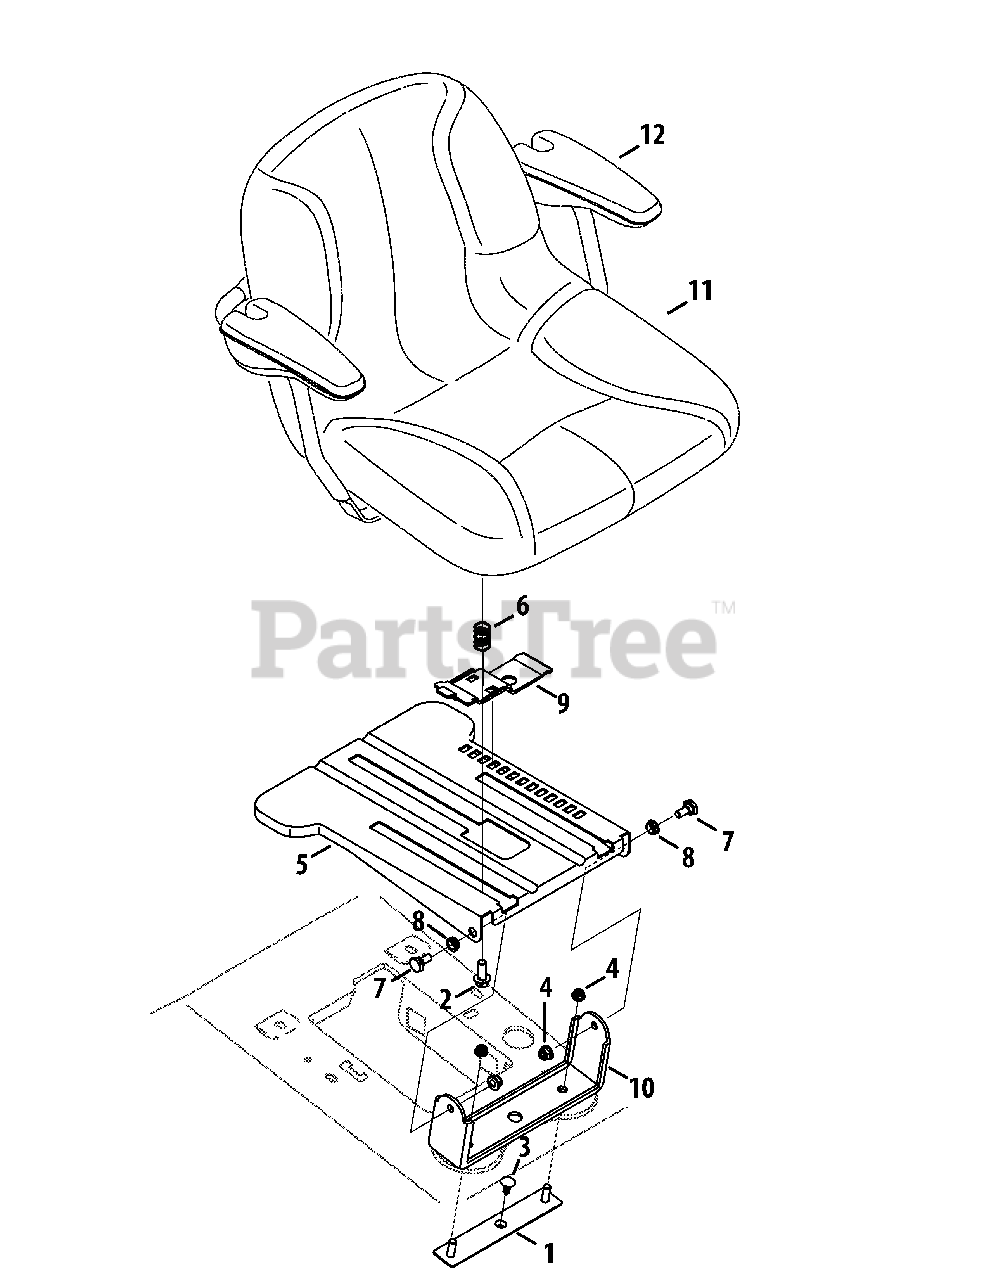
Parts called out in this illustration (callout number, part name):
1	Seat Pivot Plate Assembly
2	Hex Flange Screw, 3/8/16, .875, Gr5
3	Ratchet Clip
4	Nut, Flange Lock, 5/16-18, Grf
5	Bracket, Mounting, Seat
6	Compression Spring, .68 x 1.065 x .055
7	Shoulder Screw, .435 x .178, 5/16 x .56
8	Flange Bearing, .4385 ID
9	Seat Lever
10	Pivot Bracket, Tall
11	Seat, High
12	Arm Rest Kit
